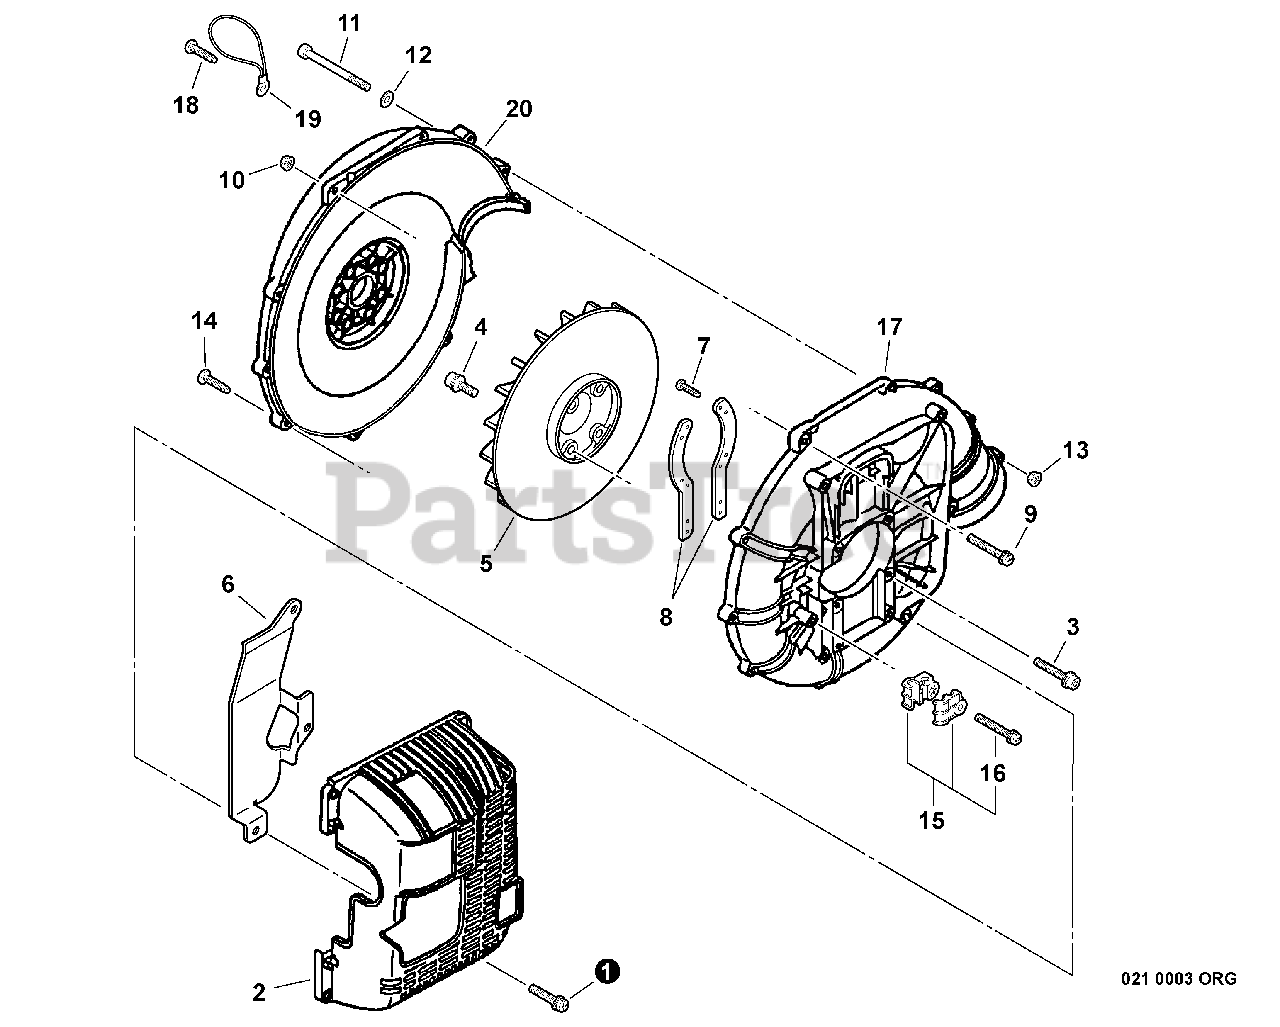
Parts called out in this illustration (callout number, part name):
1	SCREW 5×18
2	COVER, ENGINE
3	SCREW 5×32
4	BOLT 5×20
6	INSULATOR, MUFFLER
7	SCREW TAPPING 3×12
8	BRACKET, ENGINE
9	SCREW 5×40
10	NUT, FLANGE M5
11	BOLT 5×60
12	WASHER, FLAT 5.5×10×0.8
13	NUT, FLANGE M5
14	SCREW 5×30
15	CABLE HOLDER KIT
16	SCREW 5×25
17	COVER, FAN - OUTER
18	SCREW 5×16
19	STRAP, SAFETY
20	COVER, FAN - INNER
